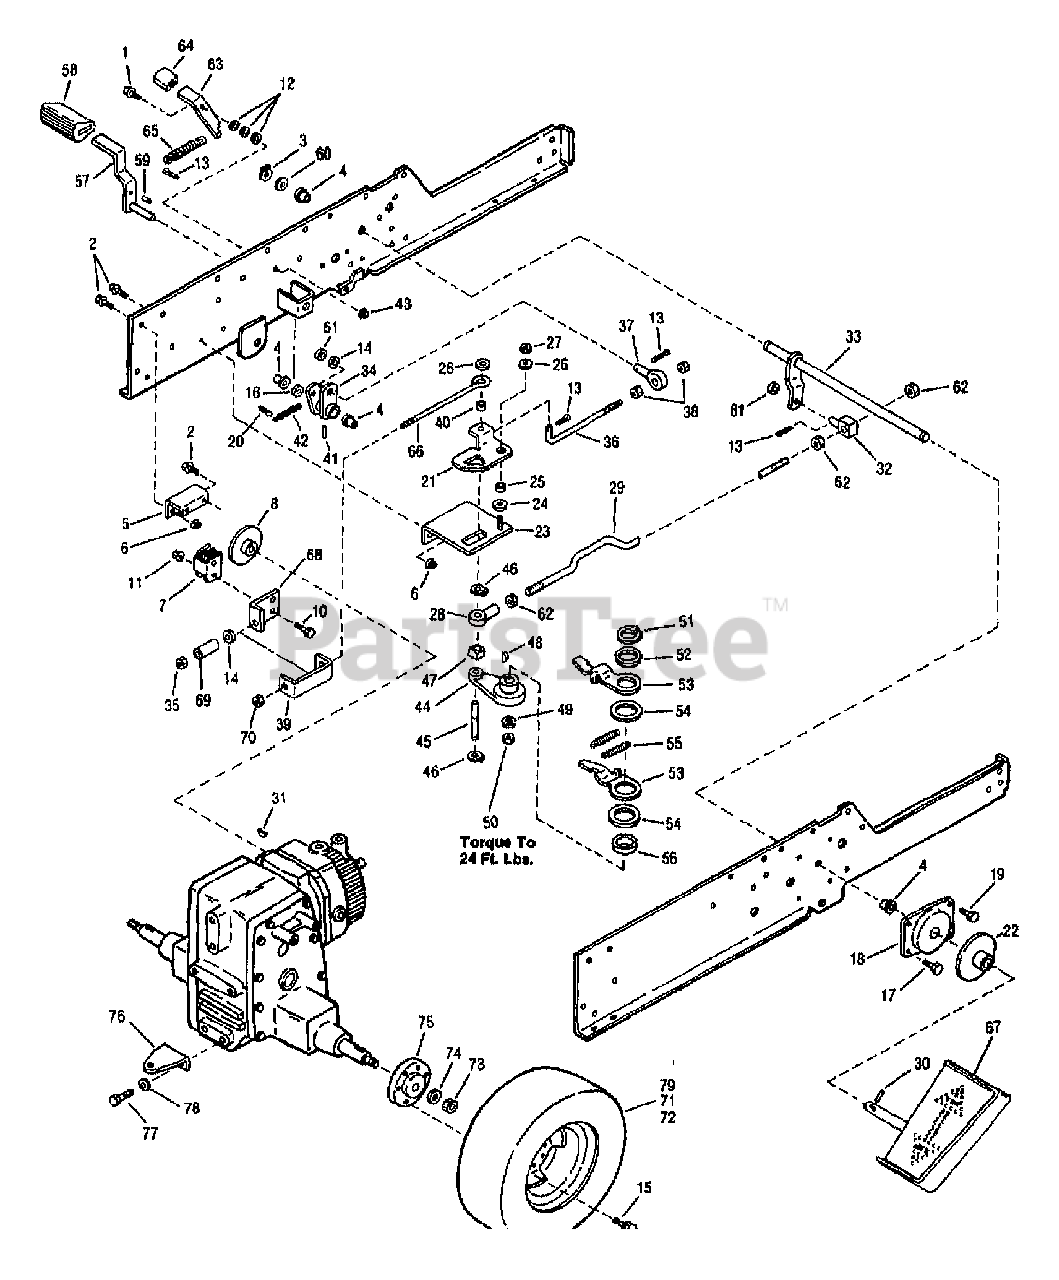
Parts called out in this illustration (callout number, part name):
1	SCR-HFLK 3/8-16X1.00 ZP
3	RING-RETAIN .625 ID
4	BEARING-FLANGE
5	BRKT-TRANSAXLE
6	NUT-HFLK 3/8-16 ZP
7	KIT-BRAKE
8	BRAKE-DISC
10	SCR-HH 1/4-20X.75 G5 ZP
11	NUT-HF/LK 1/4-20 ZP
12	WASHER-FLAT 3/8 SAE
13	PIN-COTTER .09X.75 ZP
14	WASHER-FLAT 5/16 SAE
15	BOLT-HUB
16	SPACER-.875X.626X.221
18	CLUTCH
19	SCR-SEMS MACH
20	PIN-COTTER .120X1.00 ZP
21	PLATE-NEUTRAL
22	ASSM-CONTROL DISC
23	PLATE-NEUTRAL
24	WASHER-1.75X.39X.059
25	SPACER-.625X.4X.2
26	WASHER-FLAT 3/8 SAE
27	NUT-H/LK 3/8-16
28	ROD-END
30	PIN-ROLL
31	KEY-WOODRUFF .25X.75
32	SWIVEL
33	ASSM-SHAFT
34	ASSM-BRAKE ARM
35	NUT-HEX 5/16-18 ZP
37	SWIVEL
38	NUT-HEX/JAM 3/8-16
39	BRAKE-RETURN
40	SPACER
41	PIN-DRIVE .187X1.0
42	SPRING
43	NUT-LOCK 3/8-16
44	ARM-SPEED CONTROL
45	PIN-CONTROL
46	RING-RET.EXT .437 ID
48	KEY-WOODRUFF 1/8 X 5/8
49	WASHER-1.06X.531X.1 ZP
50	NUT-H/LK 1/2-13
51	RING-RET
52	WASHER
54	WASHER-THRUST
55	SPRING
56	BEARING
57	ASSM-PEDAL
58	FOOT REST
59	PIN-ROLL .188X.75
60	WASHER-1.115X.637X.06
61	WASHER-.632X.39X.0329
62	NUT-HEX/JAM 7/16-20
65	SPRING
68	EXT-BRAKE ARM
69	SLEEVE
70	NUT-H/LK 5/16-18
72	STEM-VALVE
73	NUT-H/LK 3/4-10
74	SPACER-1.812X.765X.179
75	HUB-WHEEL
76	BAR-DRAW
77	SCR-HH 1/2-13X1.25 G5 ZP
78	WASHER-LK .5
79	ASSM-WHEEL
